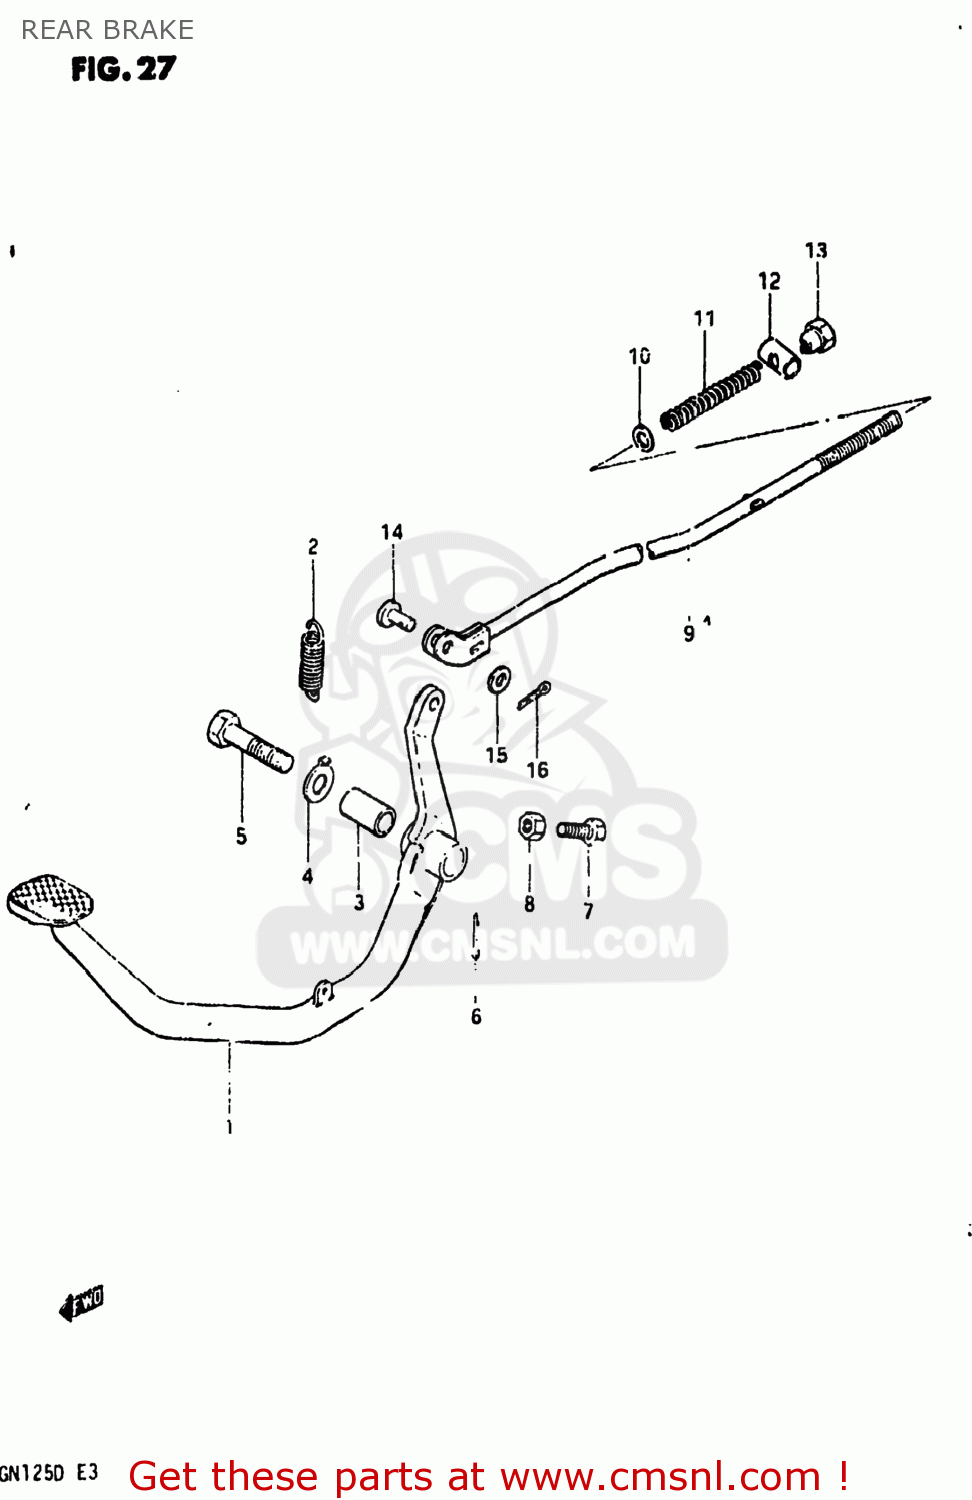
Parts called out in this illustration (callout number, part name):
1	PEDAL,BRAKE
2	SPRING
3	SPACER,BRAKE PEDAL
4	WASHER
5	BOLT 10X52
6	PIN 20X20
7	SCREW(6X23)
8	NUT
9	ROD ASSEMBLY,REAR BRAKE
10	WASHER
11	SPRING
12	PIN(11X18)
13	NUT
14	PIN(L:13.5)
15	WASHER
16	PIN 20X20
